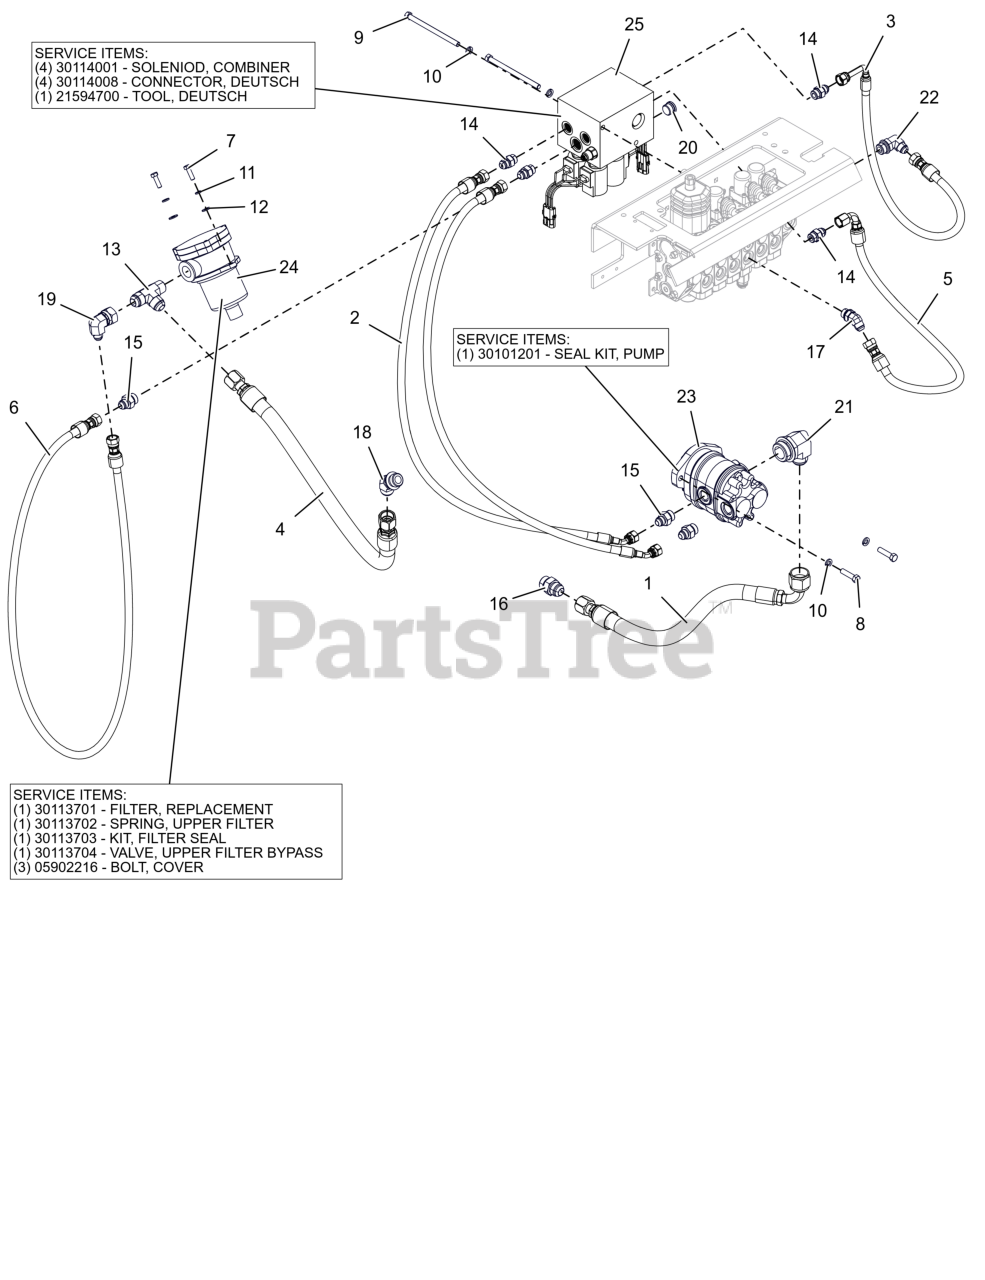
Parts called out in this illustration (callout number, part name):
1	HOSE, HYD .750" X 26.50" LG
2	HOSE, HYD .375" X 58.25" LG
3	HOSE, HYD .375" X 21.75" LG
4	HOSE, HYD .750" X 44.75" LG
5	HOSE, HYD .375" X 24.25" LG
6	HOSE, HYD .375" X 63.50" LG
7	BLT,HEX .31-18X1.00 G5 ZCC
8	BLT, HEX 0.375-16X1.5 GR8 ZCC
9	BLT, HEX 0.375-16X5.5 GR8 ZCC
10	WSHR,LK-REG .375X.094 ZCC
11	WSHR,LK-REG .312X.078 ZCC
12	WSHR, FLT .312X.734X.065 ZCC
13	BLT-SHLDR .375X4.50X.31-18
14	FITTING, HYDRAULIC 6400 8-8
15	FITTING, HYDRAULIC 6400 8-10
16	FITTING, HYDRAULIC 6400 12-12
17	FITTING, HYDRAULIC - 6802 8-8
18	FITTING, HYDRAULIC 6802 12-12
19	FITTING, HYDRAULIC 6500 8-12
20	PLUG, HEX - CSK .875 ORB
21	FITTING, HYDRAULIC 6801 16-20
22	FITTING, HYDRAULIC - 6801 8-10
23	PUMP, HYDRAULIC
23	SEAL KIT, PUMP
24	FILTER, HYD - INTANK
24	VALVE, COMBINER
24	SOLENIOD, COMBINER
24	CONNECTOR, DEUTSCH
24	TOOL, DEUTSCH
25	VALVE, HYD - COMBINER ASSY
25	VALVE, COMBINER
25	SOLENIOD, COMBINER
25	CONNECTOR, DEUTSCH
25	TOOL, DEUTSCH
